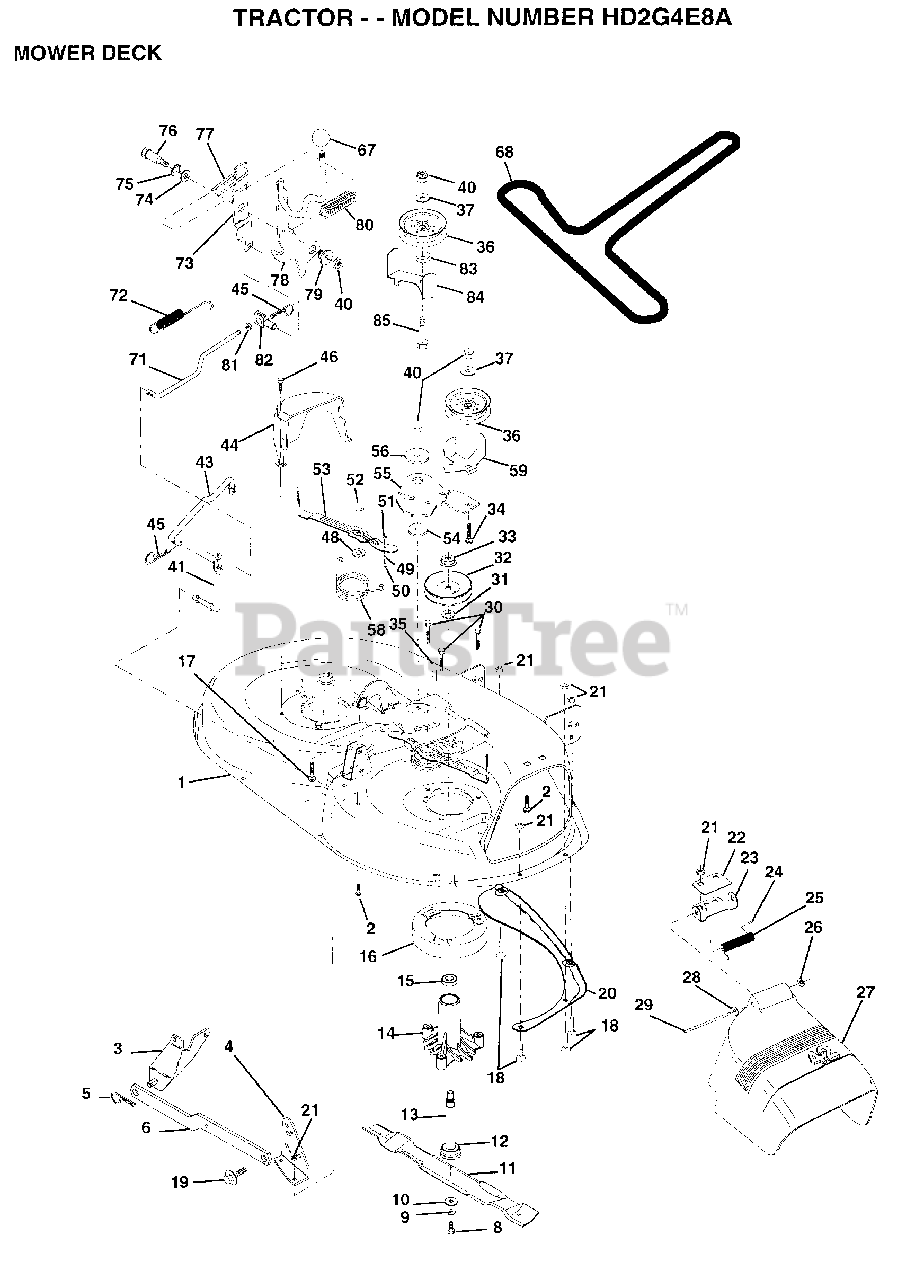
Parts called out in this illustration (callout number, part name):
1	DECK.WELD.42.
2	BOLT
3	BRKT ASM SWAY BAR
4	BRKT DECK SW BAR
8	BLADE BOLT
10	WASHER.HARD.BLADE
11	"BLADE.42"" HIPERF"
12	BEARING.BALL
14	HSG ASM MANDREL
15	BEARING
16	STRIPPER RND MWR
17	BOLT RDHD 3/8-16
18	BOLT
19	BOLT SHD 5/16-18
22	STIFFENER BRKT
23	DEFLECTOR BRKT
24	CAP-SLEEVE LT
25	SPRING TORSION
26	NUT PUSH M
27	DEFLECTOR.SHIELD
28	WASHER
29	HINGE ROD
31	WASHER
34	BOLT
35	XMAS TREE FASTNER
36	FLAT IDLER PULLEY
37	WASHER
41	PIVOT ROD
43	ROD CLUTCH W/NIBS
44	GUARD MAND LH BLK
45	RETAINER M
46	SCREW.1/4-20X5/8
48	HARD SMALL WASHER
50	SHOULDER BOLT
51	LOCKNUT
52	BOLT.SHLD.5/16-18
53	BRAKE PAD ARM ASM
54	HARDENED WASHER
56	SPACER RETAINER
58	SPRING TORSN BRAK
59	GUARD IDLER TUV
67	KNOB T (1/2-HOLE)
68	BELT.V.T-PATH
71	ROD CLUTCH 38/42
72	RETURN SPRING
73	CLUTCH ARM SECOND
74	WASHER
75	RING
76	SHOULDER BOLT
77	SPRING KEEPER
78	LEVER ASM CLT PRM
79	BUSHING
81	NUT
82	TRUNION ADJ
83	WASHER
85	BOLT RDHD 3/8-16
113	SCREW
114	NUT
116	BOLT M
117	WHEEL.GAGE.BLK.PL
118	LOCKNUT
119	WASHER
120	WASHER
121	BRACKET.EXTRD.GWL
